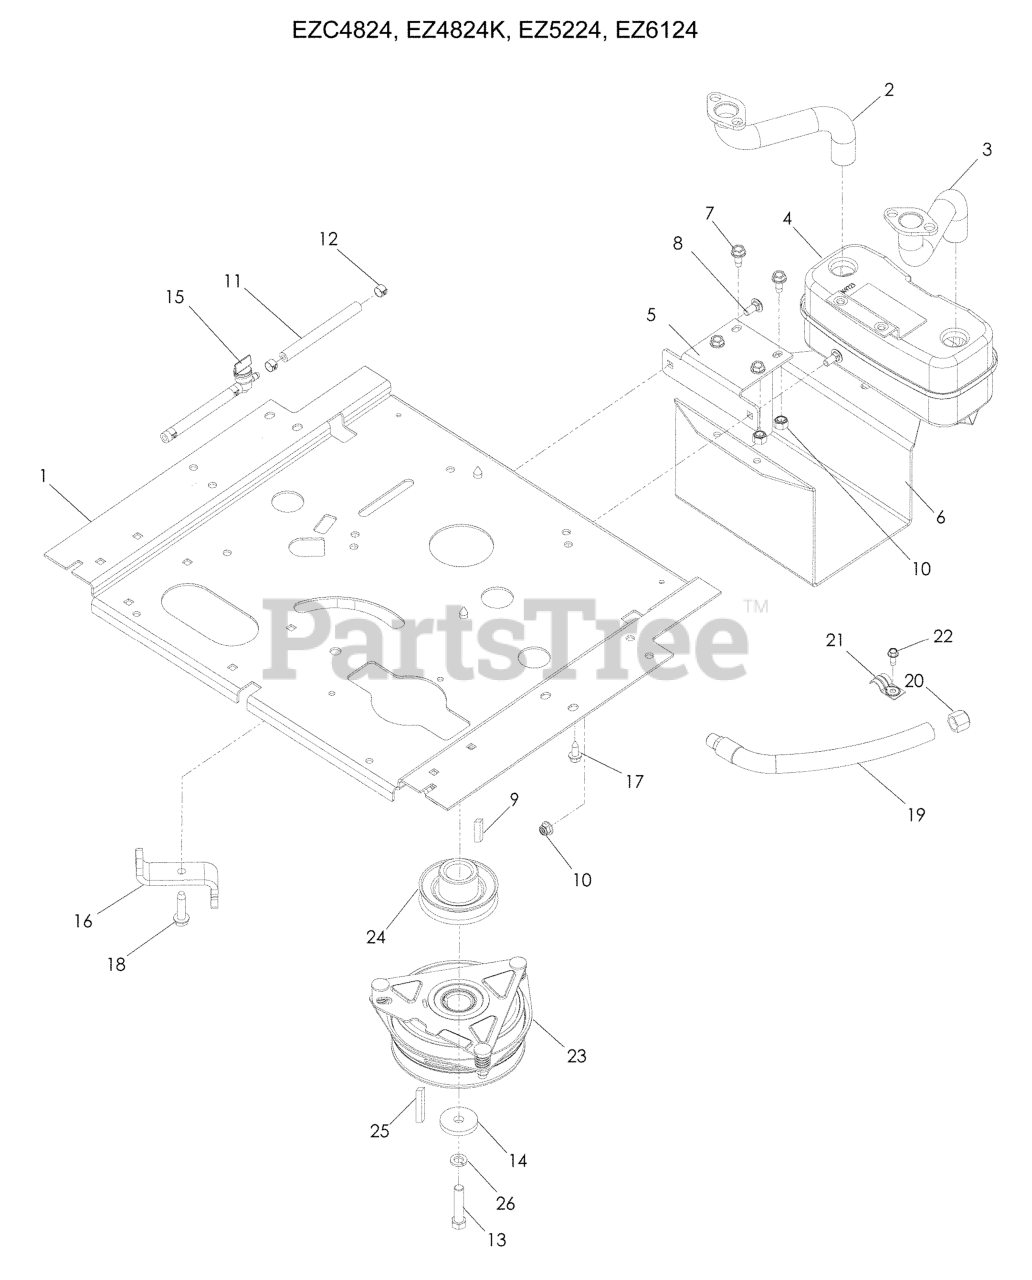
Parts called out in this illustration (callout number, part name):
1	PLATE, ENGINE, BLACK
2	RP.PIPE-EXHAUST LH
3	RP.PIPE-EXHAUST RH
4	MUFFLER ASM TWIN
5	BRACKET, MUFFLER, BLACK
6	GUARD, MUFFLER, BLACK
7	BOLT 5/16-18 X 3/4
8	BOLT 5/16C X 3/4" CARRIAGE
9	KEY 1/4 SQ X 1.0
10	5/16-18 NYLOC FLANGE NUT
11	FUEL LINE 5"
12	HOSE CLAMP
13	HCS 7/16-20 X 2 G8 ZN
14	SPINDLE WASHER
15	FUEL VALVE
16	STOP, CLUTCH, OGURA, BLK
17	HHFS 3/8-16 X 1.0 THD FORMING
18	BOLT 3/8-16 X 1 1/2 ZINC CLEAR
19	OIL DRAIN HOSE
22	SCREW 1/4 X 5/8
23	CLUTCH, 150 FT/LBS
24	PULLEY, 4.5"
25	KEY 1/4 SQ X 2
26	WASHER 7/16 LOCK
